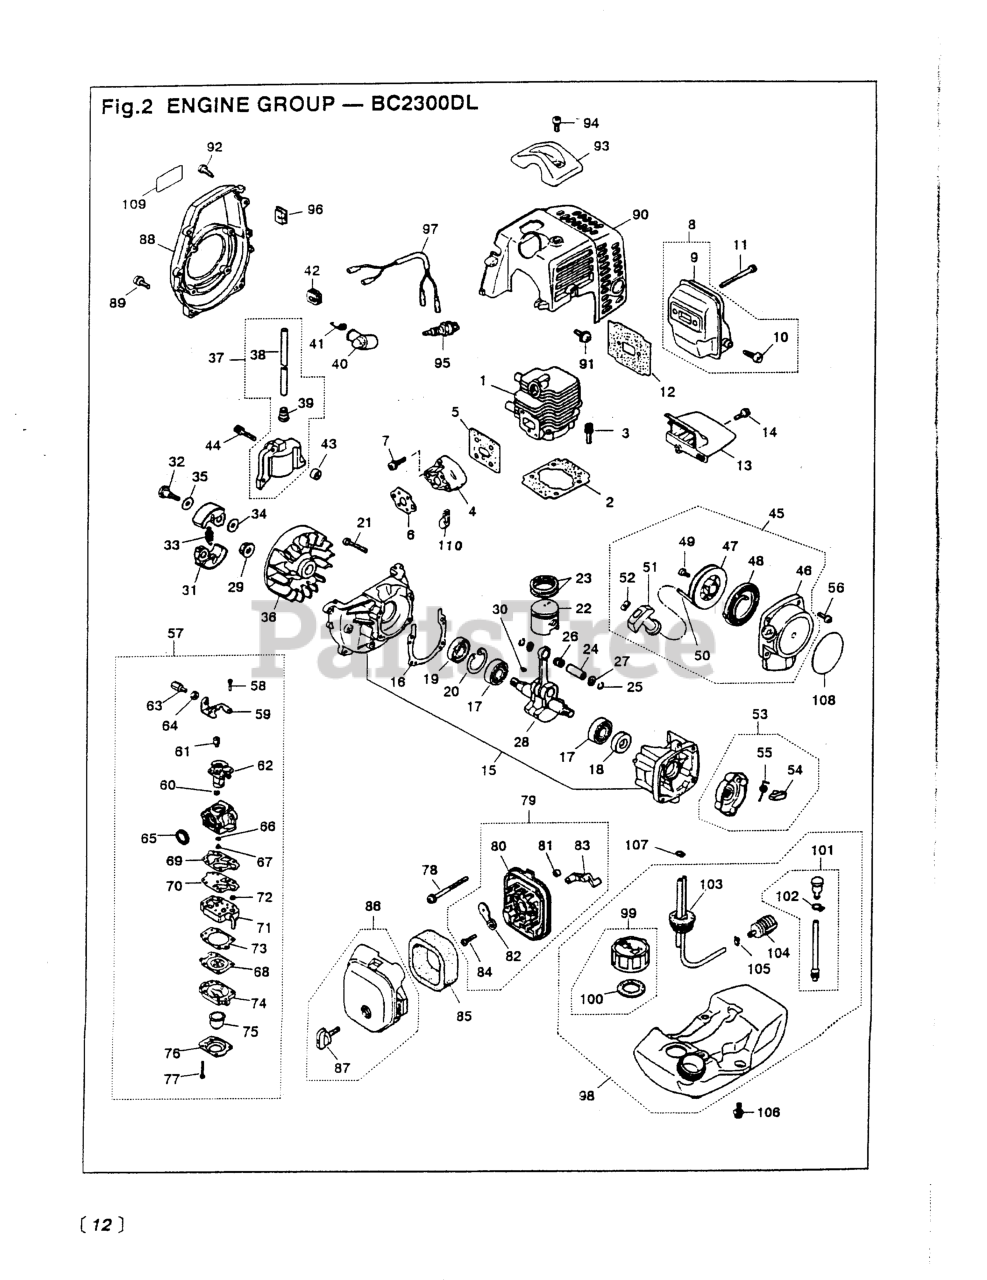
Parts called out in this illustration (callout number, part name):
1	CYLINDER
3	BOLT, M5 X 22
7	SCREW, M5X20 (RPLS.1400-75510)
9	MUFFLER ASSY (USE 5913-15100)
10	ARRESTER (RPLS 5850-15140)
11	BOLT, M5 x 50
12	GASKET, MUFFLER
14	SCREW, M4 X 16
15	CRANKCASE
17	BEARING
18	SEAL, OIL (RPLS 1100-21210)
19	SEAL, OIL (RPLS 1140-21220)
20	RING, SNAP, M28 x 1.2
21	BOLT, M5 X 30
22	PISTON (REPLACES 1140-41110)
23	RING, PISTON (RPLS 1850-41210)
24	PIN, PISTON 5x8x26
25	RING, SNAP (RPLS 1101-41320)
27	WASHER
28	CRANKSHAFT (RPLS 1850-42000)
30	KEY
32	BOLT
33	SPRING, CLUTCH (RPLS-51220)
34	WASHER, FLAT (USE 182303)
38	CORD
39	CAP
41	SPRING
42	GROMMET
44	BOLT
45	RECOIL ASSEMBLY
46	CASE
47	REEL
48	SPRING, SPIRAL
49	SCREW (RPLS -75150)
51	KNOB
52	PLATE, STOPPER
53	PULLEY ASSY (RPLS -75210)
54	RATCHET (RPLS 1850-75220)
55	SPRING, RETURN
56	SCREW, M4 X 16
57	CARBURETOR
58	SCREW
60	RING
61	SWIVEL
62	VALVE ASSY
63	SCREW, CABLE ADJUSTER
64	NUT, CABLE ADJUSTER
65	RING, PACKING
66	RING, O
67	JET
68	DIAPHRAGM (USE 4810-81260)
69	GASKET, PUMP
70	DIAPHRAGM
71	BODY, PUMP
73	GASKET, DIAPHRAGM
74	BODY, PURGE
75	PUMP, PRIMING
76	COVER, PUMP
77	SCREW
78	SCREW, M5 X 55
80	BODY
81	SLEEVE
82	PLATE, CHOKE (RPLS-82130)
83	LEVER, CHOKE
84	SCREW (REPLACES 50030272)
85	ELEMENT
89	SCREW, M5X20 (RPLS.1400-75510)
91	SCREW, M5 x 12
92	SCREW, HOUSING
93	GUARD, PLUG
94	SCREW,M5 X 14 (RPLS 1400-15510
97	CORD COMP (RPLS -73200)
99	CAP (RPLS -85200)
100	PACKING
102	CLIP
103	PIPE COMPLETE
104	FILTER ASSY
105	CLIP (REPLACES 2841-31280)
106	SCREW
107	CLIP
109	LABEL, FAN COVER
110	CLAMP
